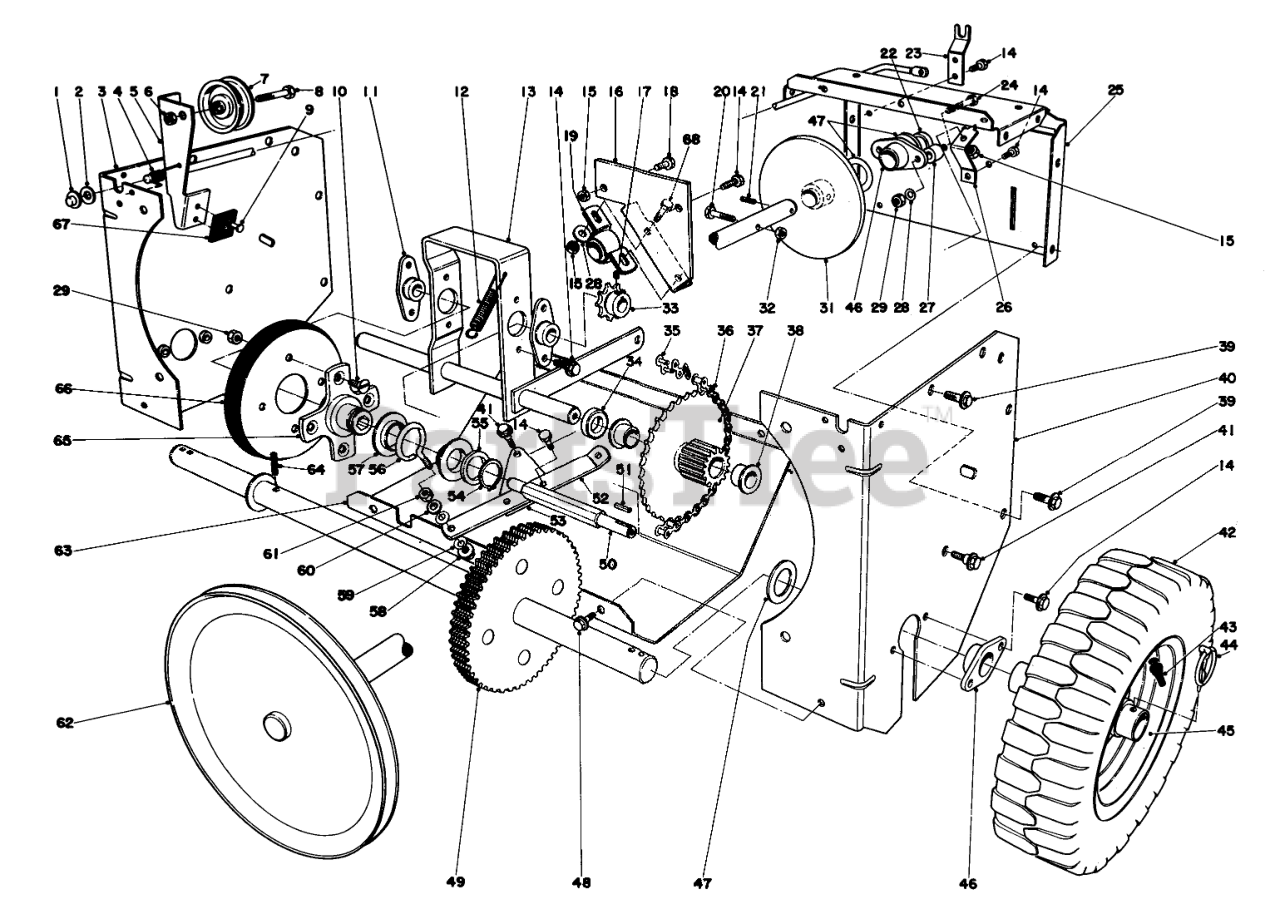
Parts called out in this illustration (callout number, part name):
1	PUSH NUT
2	WASHER-FLAT
3	RH TRACT SIDE PLT R
4	TORSION CLUTCH SPRING
5	Clutch Rod (Incl. Ref. #9&67)
6	NUT-HEX
7	PULLEY-IDLER
8	SCREW-HH
9	.185 DIA X .375 RT +
10	5/16-18X5/8 FLT HD MS
11	BEARING-WHEEL, FRICTION
12	TENSION SPRING
13	PIVOT SHAFT WA B
14	SCREW-HWHTF
15	NUT-LOCK, NI
16	SHAFT SUPT BRKT B
17	SCREW-HSH
18	SCREW-HH
19	PILLOW BLOCK BRG
20	SCREW-HH
21	PIN-ROLL, SLOTTED
22	DRIVE SHAFT SPACER
23	CLUTCH ROD SUPPORT
24	SCREW-HH
25	CENTER FRAME R
26	PIVOT BRACKET
27	BRG STANDOFF
28	WASHER-PLAIN
29	Nut
30	FRICTION PLT WA
32	NUT-LOCK, CONE
33	SPROCKET
34	COSHAFT SPACER
35	LINK-CHAIN
36	ROLLER-CHAIN
37	Gear & Bushing (Incl. Ref. #38)
38	BUSHING
39	SCREW-HHFTF
40	LH TRACT SIDE PLT R
41	SHOULDER SCREW
42	Tire
43	STEM-VALVE
44	PIN-LYNCH
45	Wheel
46	AXLE BEARING
47	WASHER
48	SCREW-HWH
49	AXLE & GEAR WA
50	FRICTION WHL SHAFT
52	SHIFT LINKAGE
53	PIVOT PLATE
54	RING-RETAINING
55	WASHER-THRUST
56	SLIDER RING COLLAR
57	SLIDER RING
58	NUT-LOCK, FLANGE
59	WASHER-SPRING
60	WASHER-FLAT
61	Nut
62	PULLEY/SHFT WA
63	LOWER SHIELD R
64	PIN-ROLL, SLOTTED
65	TRACTION DISC HUB
66	Disc
67	BRAKE PAD
68	SCREW-HH
